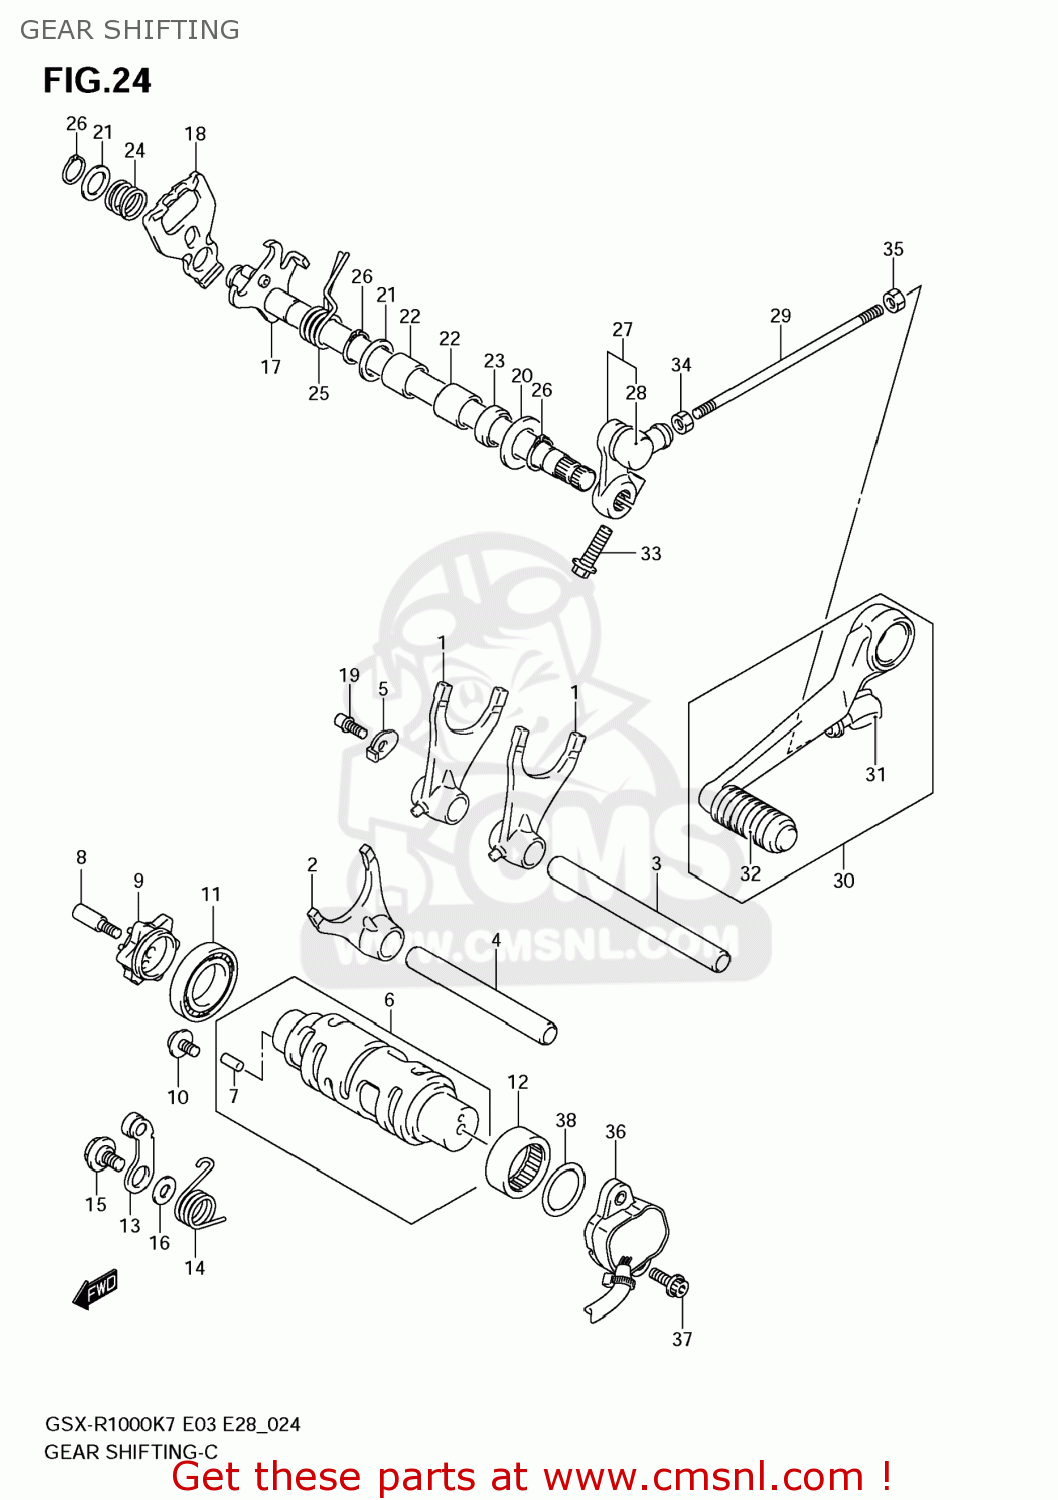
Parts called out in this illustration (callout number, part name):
1	FORK,GEAR SHIF
2	FORK,GEAR SHIF
3	SHAFT,SHIFT FORK NO.2(L:132)
4	SHAFT,GEAR SHIFT FORK
5	RETAINER,GEAR SHIFT FORK SHAFT
6	CAM,GEAR SHIFT
7	PIN
8	BOLT,GEAR SHIF
9	PLATE,GEAR SHIFT CAM
10	SCREW(6X12)
11	BEARING(25X47X8)
12	BEARING(25X32X12)
13	STOPPER,SHIFT CAM
14	SPRING,SHIFT CAM STOPPER
15	BOLT(6X14.3)
16	WASHER
17	SHAFT,GEAR SHIFT
18	PLATE,GEAR SHIFT CAM DRIVE
19	STOPPER,GEAR SHIFT ARM
20	WASHER(14X29X0.8)
21	SHIM(14X22X1)
22	BEARING(14X20X12)
23	SEAL,OIL(14X22X6)
24	SPRING
25	SPRING
26	CIRCLIP
27	ARM,GEAR SHIFT LINK
28	COVER,DUST
29	ROD,GEAR SHIFT LINK
30	LEVER ASSY,GEAR SHIFT
31	COVER,DUST
32	RUBBER,GEAR SHIFT PEDAL
33	BOLT(6X25)
34	NUT
35	NUT
36	SENSOR ASSY,GEAR POSITION
37	BOLT(5X16)
38	O RING(D:2.4,ID:25.7)
